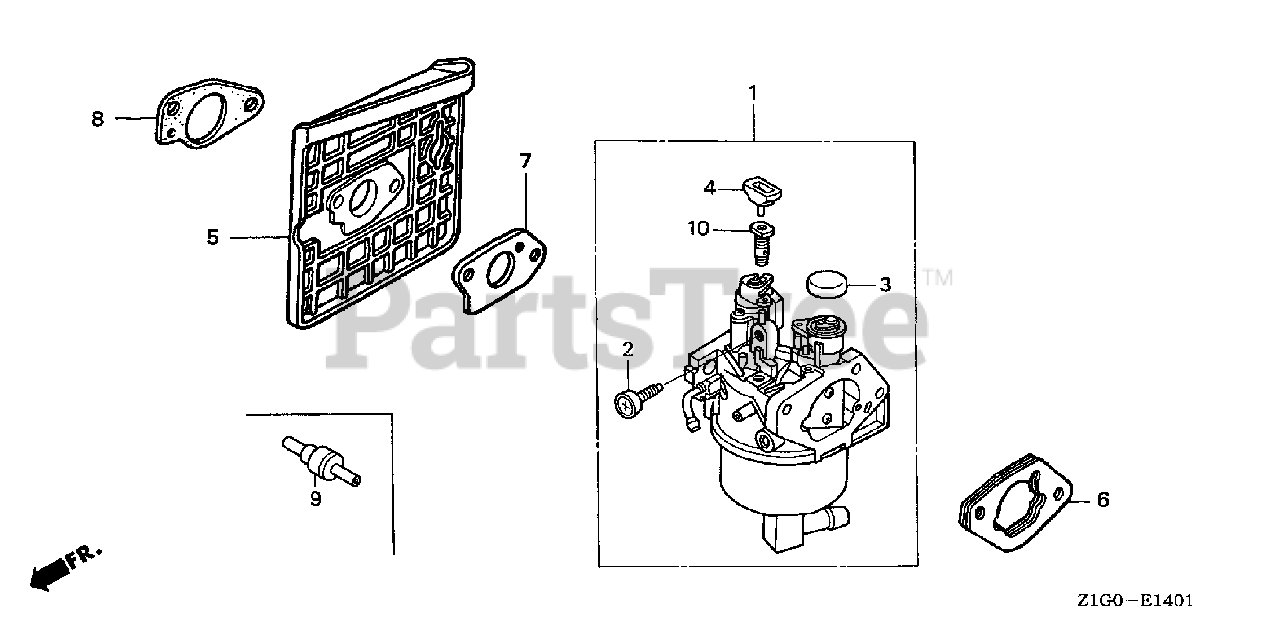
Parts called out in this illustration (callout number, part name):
1	CARBURETOR ASSY. (BEL7A C)
2	SCREW, THROTTLE STOP
3	CAP, CHOKE DUST
4	COLLAR, SETTING
5	INSULATOR, CARBURETOR
6	SPACER, CARBURETOR
7	GASKET, CARBURETOR
8	GASKET, INSULATOR
9	VALVE, DASHPOT CHECK
10	JET, PILOT (#45)
